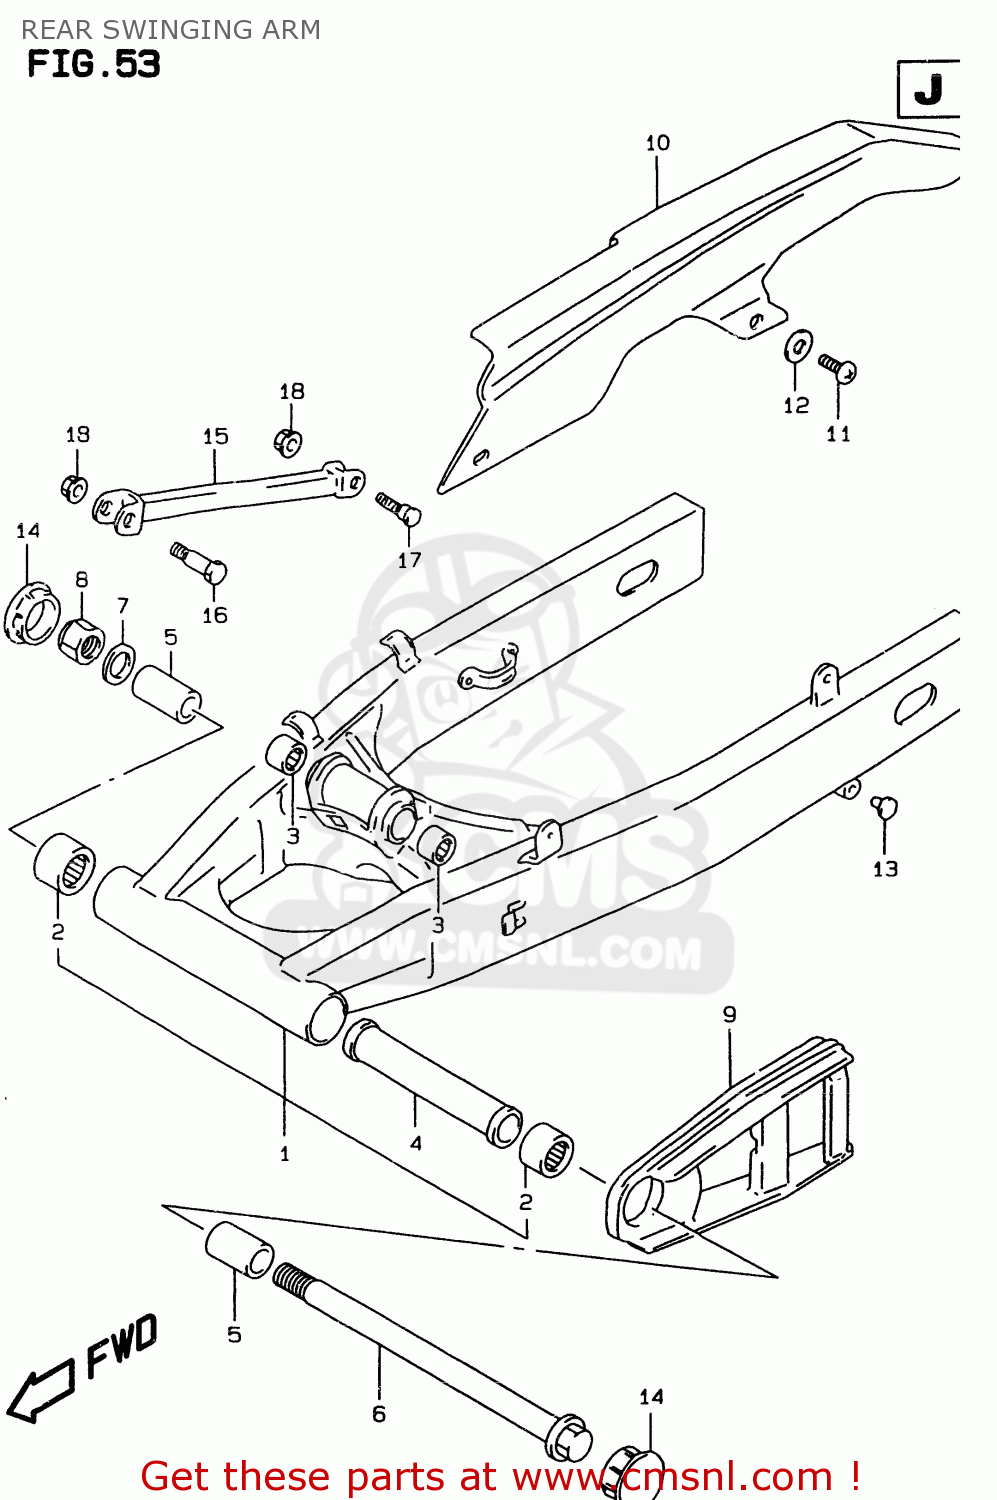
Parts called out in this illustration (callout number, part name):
1	SWINGINGARM ASSY,RR
2	BEARING(25X33X35)
3	BEARING(17X24X25)
4	SPACER(20.8X27.2X146)
5	SPACER,RR SWGARM PIVOT
6	SHAFT,RR SWINGINGARM PIVOT
7	WASHER(18.5X28X2.6)
8	NUT
9	BUFFER,CHAIN TOUCH DEFENSE
10	CASE,CHAIN
11	SCREW 6X12
12	WASHER
13	CAP(OD:12)
14	CAP,FRAME PIVOT
15	TORQUELINK,RR
16	BOLT(10X39)
17	BOLT(10X34)
18	NUT
